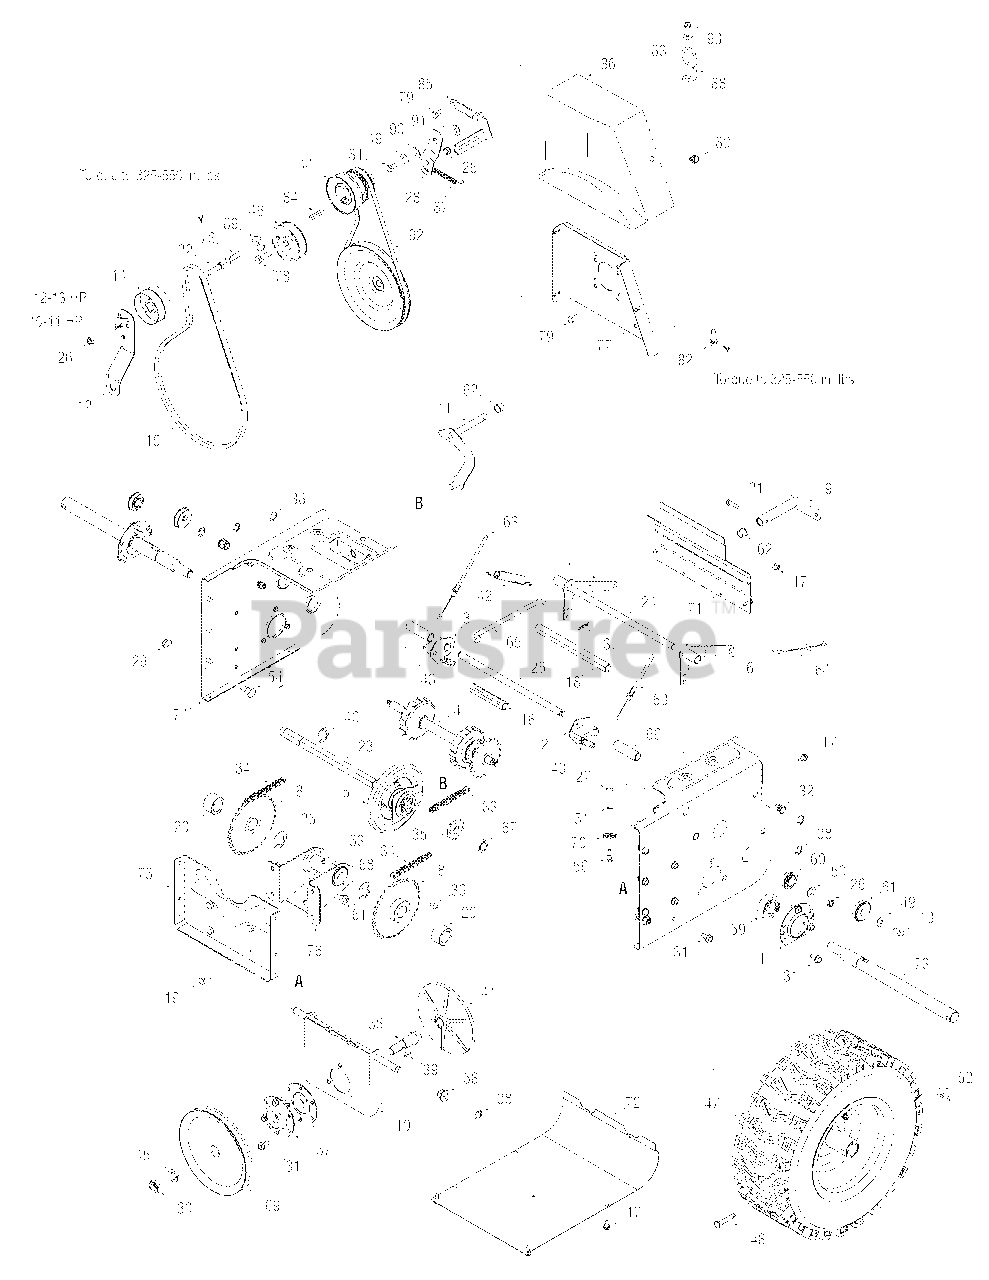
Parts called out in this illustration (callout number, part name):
1	Bearing Housing
2	LH Dog Assembly
3	RH Dog Assembly
4	Steering Shaft Assembly
5	Wheel Ass’y Bearing 6.0" OD
5	Friction Wheel Bonded
5	Hex Wash. Hd. TT Scr. 1/4-14 x .625
6	Actuator Auger Bracket Ass’y
7	Actuator Drive Bracket Ass’y
8	32T Sprocket Ass’y
9	Shift Arm Ass’y
10	Friction Drive Support
11	Shift Ass’y Rod
12	Auger Idler Bracket
13	Hex L-Bolt 5/16-18 x .62
14	Flat Idler Pulley
15	V-Belt 1/2 x 44" Lg. (12-13 HP)
15	V-Belt 1/2 x 42" Lg. (10-11 HP)
16	Spacer .51 ID x 3.66" Lg.
17	Hex Wash Hd TT Scr. 1/4-20 x .625
18	Spacer .51 ID x 7.895" Lg.
19	Hex Hd. C-Sunk Scr. 3/8-16 x .880 Gr. 5
20	Spacer 1.0 ID x 1.5" Lg.
21	Hex Bolt 1/4-20 x 1.00
22	Hex Scr 3/8-24 x 1.50 Gr. 5
23	Hex Drive Shaft
24	Actuator Shaft
25	Retaining Ring
26	Hex Nut 3/8-24
27	Hex Nut 1/4-28
28	Drive Idler Bracket
29	Flange L-Nut 3/8-16 Gr. F Nylon
30	Hex Jam Locknut 5/8-18 Gr. 5 Nylon
31	TT Screw, 5/16-18 x .75
32	Nut Insert 3/8-16 UNC
33	#41 Chain 1/2" pitch x 36 links- Endless
34	#420 Chain 1/2" pitch x 40 links-Endless
35	10T Sprocket #41 x .500
36	Woodruff Key
37	Int. Cotter Pin 5/16 DIA
38	E-ring
39	No. 61 Hi-Pro Key 3/16 x 5/8
40	Retaining Ring E-Type .875 dia.
41	Aluminum Drive Plate
42	Idler Extension Spring
43	Extension Spring .47 OD x 2.03 Lg.
44	Pulley, Dbl 3.25 OD
45	Lockwasher 5/16 ID
46	Flat Idler Pulley 3.0 OD
47	Tire 16 x 6.5 x 8
47	Wheel Ass'y LH 16 x 4.5 x 8 X-Trac
47	Wheel Ass'y RH 16 x 4.5 x 8 X-Trac
47	Tire 16 x 4.5 x 8
47	Rim 16 x 4.5 x 8
48	Clevis Pin
49	Cupped Washer .345 ID x .88 OD x .06
50	Flat Washer .385 ID x .87 OD x .06
51	L-Wash 1/4 ID
52	Int. Cotter Pin
53	Grease
54	Shld. Scr. .500 Dia. x .335" Lg.
55	Drive Plate Spindle
56	Hex Shld.Scr.1/4-28 x .375
57	Bearing Hsg. Ass’y.
58	Hex Flange Bearing
59	Self aligning brg. 1.0 ID
60	Ball Bearing .5625 ID x 1.3750 x .437
61	Ball Bearing w/snap ring
62	Flange Bushing .500 ID x .627 OD
63	Steering Cable
64	Auger Idler Cable
65	Drive Clutch Rod
66	Split Spacer 1/2 x 5/8 x 2.69
67	Spacer .625 ID x 1.0 OD x .23
68	Spacer .6725ID x 1.125OD x 2.485
69	1/2" "V" Pulley .625 ID x 7.50 OD
70	Cable Guide Roller
73	Axle .995 x 12.6" Lg. (28")
73	Axle.995 x 14.10" Lg (30" & 33")
73	Axle .995 x 20.4" Lg. (45")
76	Axle Brg. Support Bracket
77	Belt Cover Bracket
78	Hex Screw 3/8-24 x 1.25 Gr. 8 Special
79	Hex Screw 5/16-24 x .625 Gr. 5
80	Hex Wash HD S-Tapp Scr 5/16-18 x .50
81	Hex HD. Cap Scr. 5/16-24 x 1.25 Lg. Gr 5
82	Hex Wash HD Tap Scr 3/8-16 x 1.00
83	Flat Washer .28 ID x .74 OD x .063
84	Square Key 1/4 x 1/4 x 1.50" Lg.
85	Belt Keeper Bracket
86	Belt Cover
87	Brake Return Ext. Spring 3.18" Lg.
88	Cable Control Wire
89	Flat Washer .406 ID x 1.25 OD x .160
90	Shoulder Spacer .25 THK
91	Flat Wash .349 ID x .879 OD x .063 (12-13 HP)
91	Spacer .33 ID x 1.01 OD x .36 (10-11 HP)
92	V-Belt 3/8 x 35.5" Lg. (12-13 HP)
92	V-Belt 3/8 x 34.4" Lg. (10-11 HP)
93	Hex Flg. L-Nut 1/4-20 Gr. F Nylon
